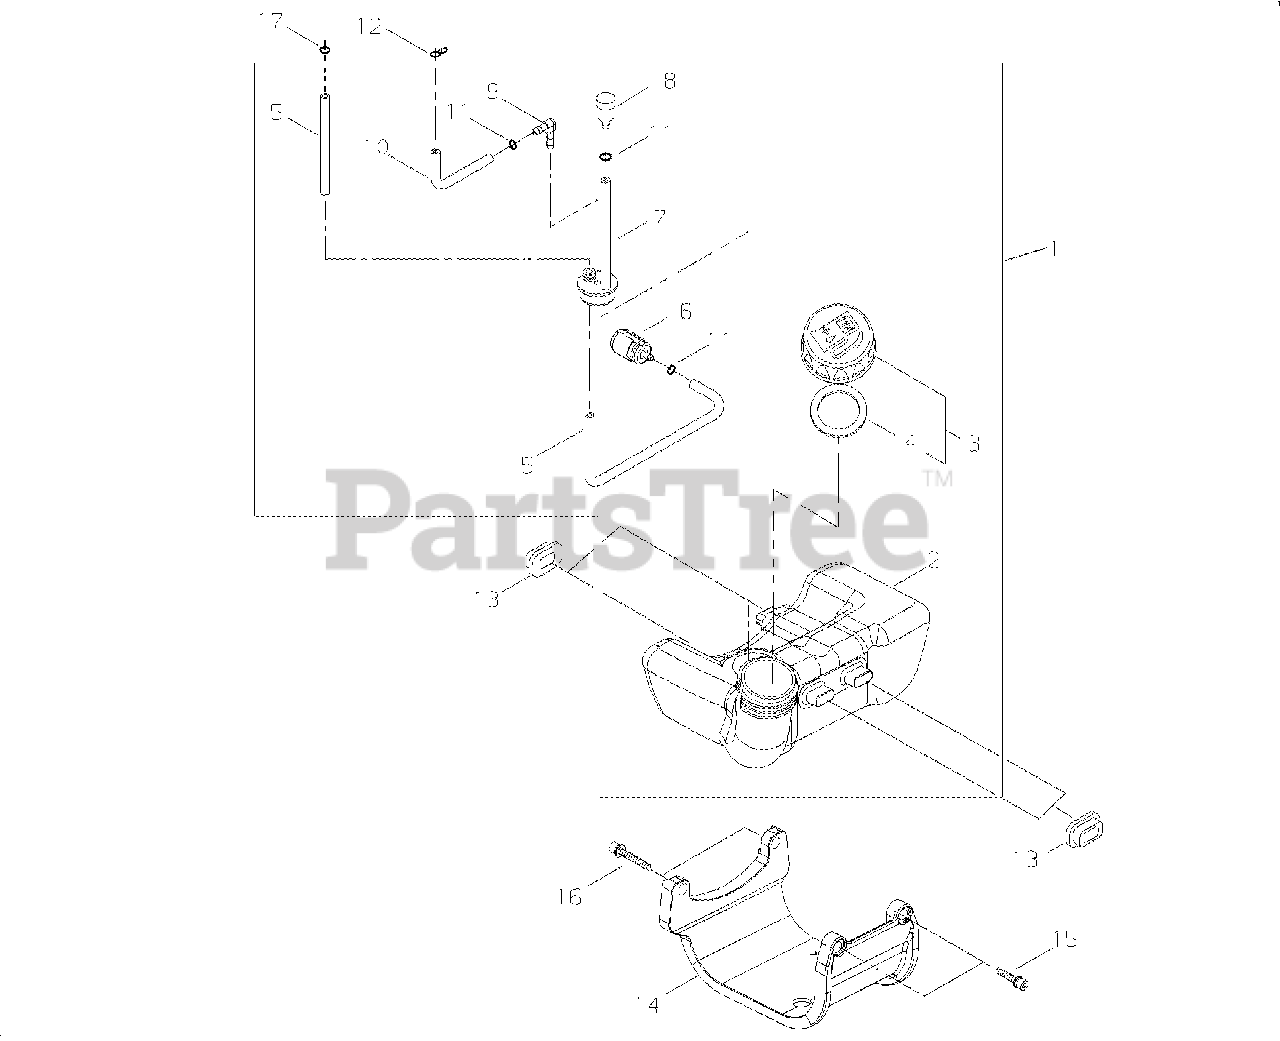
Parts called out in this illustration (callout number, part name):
1	TANK ASSY, FUEL
2	TANK, FUEL
3	CAP ASSY, FUEL
4	GASKET, FUEL CAP
5	PIPE, FUEL
6	FILTER, FUEL 125-528
7	GROMMET, FUEL W/VENT PIPE
8	VENT ASSY
9	CONNECTOR, PIPE
10	PIPE, FUEL RETURN
11	CLIP Ø6
12	CLIP, SPRING Ø5.2
13	CUSHION, FUEL TANK
14	GUARD, FUEL TANK
15	BOLT M5×18
16	BOLT M5×40
17	CLIP Ø6
